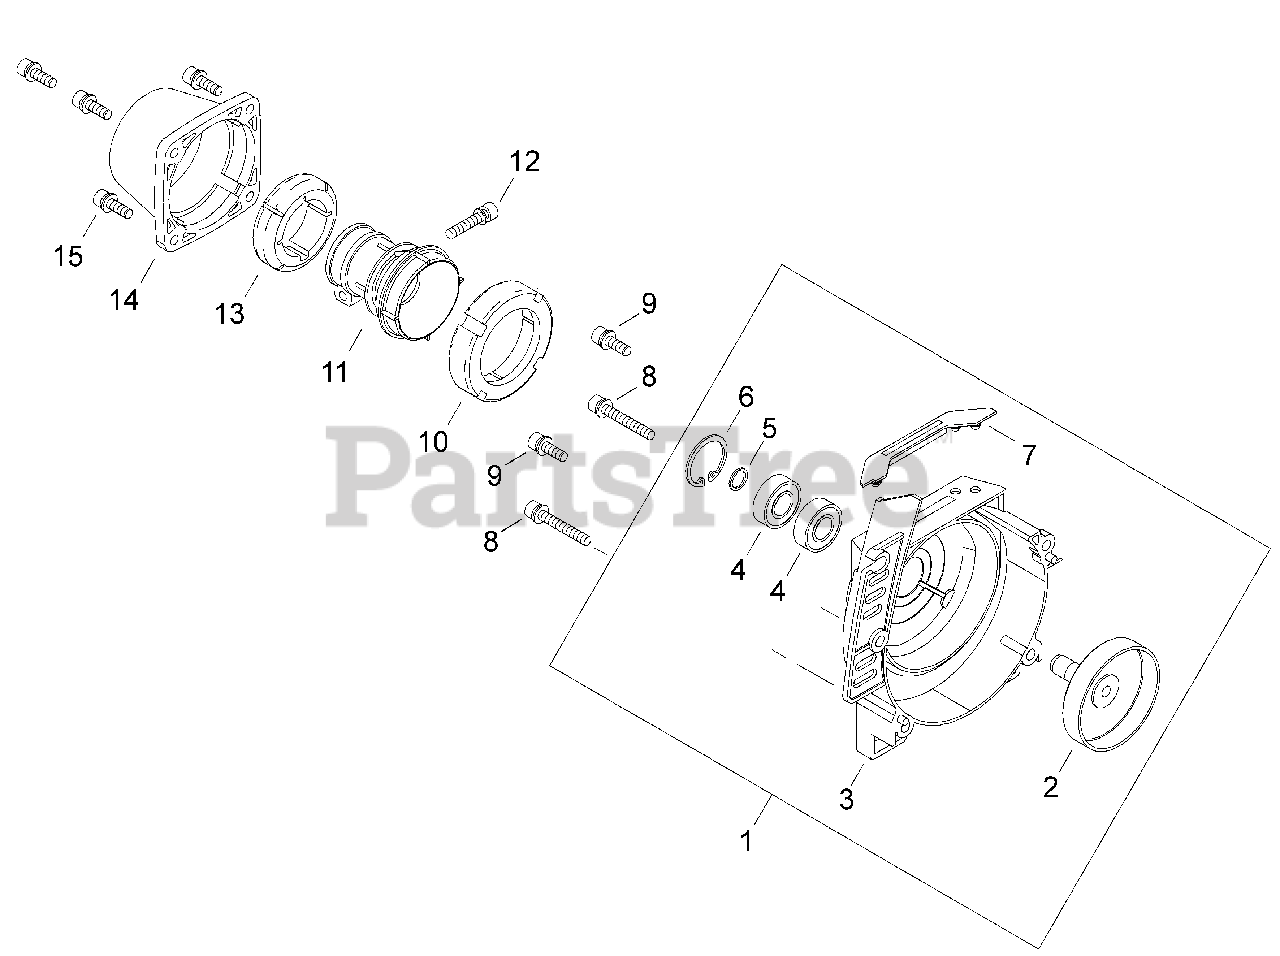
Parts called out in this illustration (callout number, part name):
1	COVER ASSY, FAN
2	DRUM, CLUTCH
3	COVER, FAN
4	BEARING, BALL 6000ZZ
5	RING, SNAP WR10
6	RING, SNAP Ø26
7	CUSHION
8	BOLT M5×45
9	BOLT M5×16
10	HOLDER, REAR CUSHION
11	CUSHION, AV
12	BOLT M5×25
13	CUSHION, FRONT
14	COVER, AV CUSHION (RED)
15	BOLT M5×16
